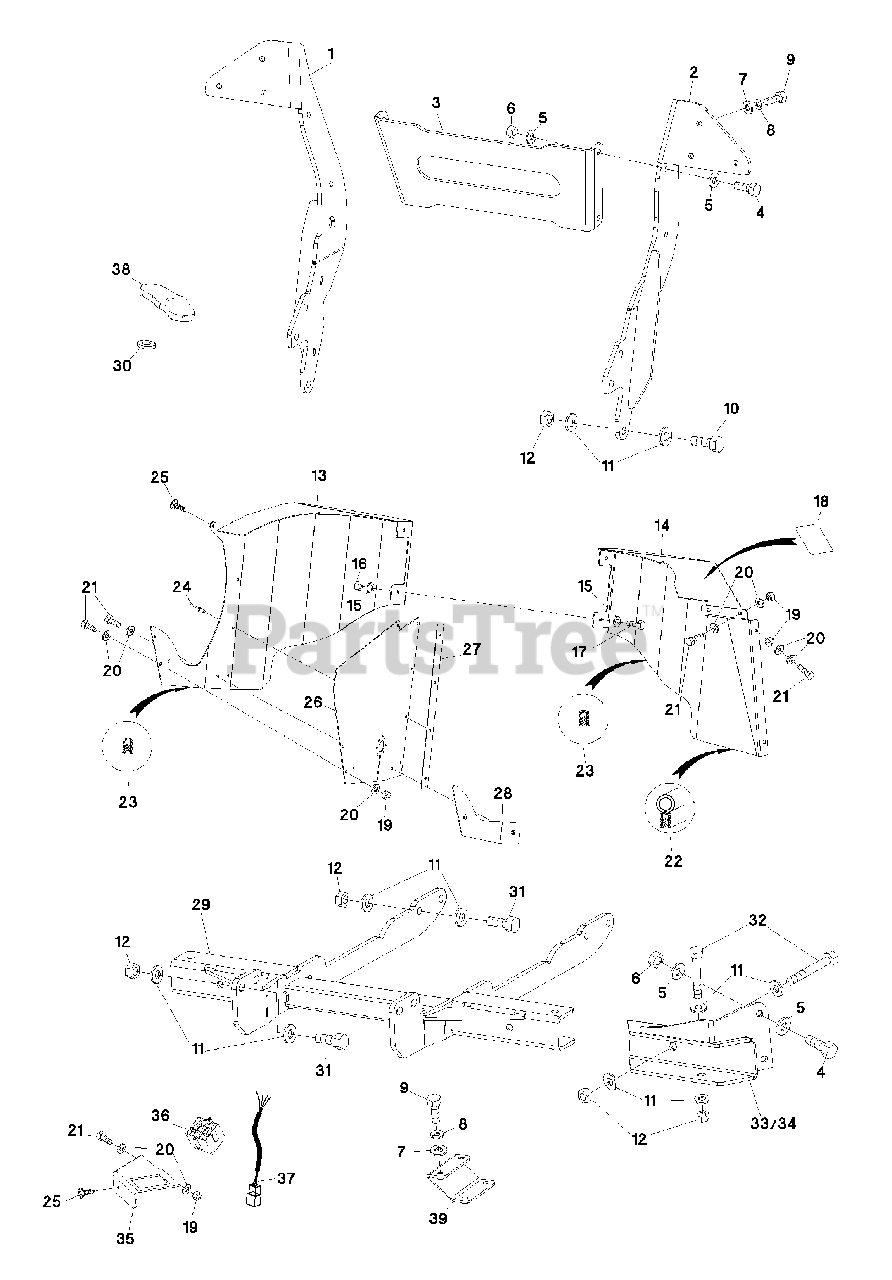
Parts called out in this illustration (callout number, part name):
1	Strut right
3	Cross-stay below
4	Hexagon head screw M10x30
5	Shim disk M10
6	Stop nut M10
7	Shim disk M8
8	Retainer ring M8
9	Hexagon head screw M8x25
10	Hexagon head screw M12x45
11	Shim disk M12
12	Stop nut M12
13	Spoiler right
14	Spoiler left
15	Shim disk M6
16	Stop nut M6
17	Hexagon head screw M6x16
19	Stop nut M5
20	Shim disk M5
21	Hexagon head screw M5x20
22	Tube profile
23	Edge-protection small
24	Blind rivet 4x12
25	Sheet metal screw 4.8x16
26	Brake pedal cover
28	Screw-on plate
29	Attachment bracket
31	Hexagon head screw M12x40
32	Hexagon head screw M12x100
33	Bracket front left
34	Bracket front right
35	Mounting fuse box
38	Safety belt fastening
39	Mounting front-loader locking device
